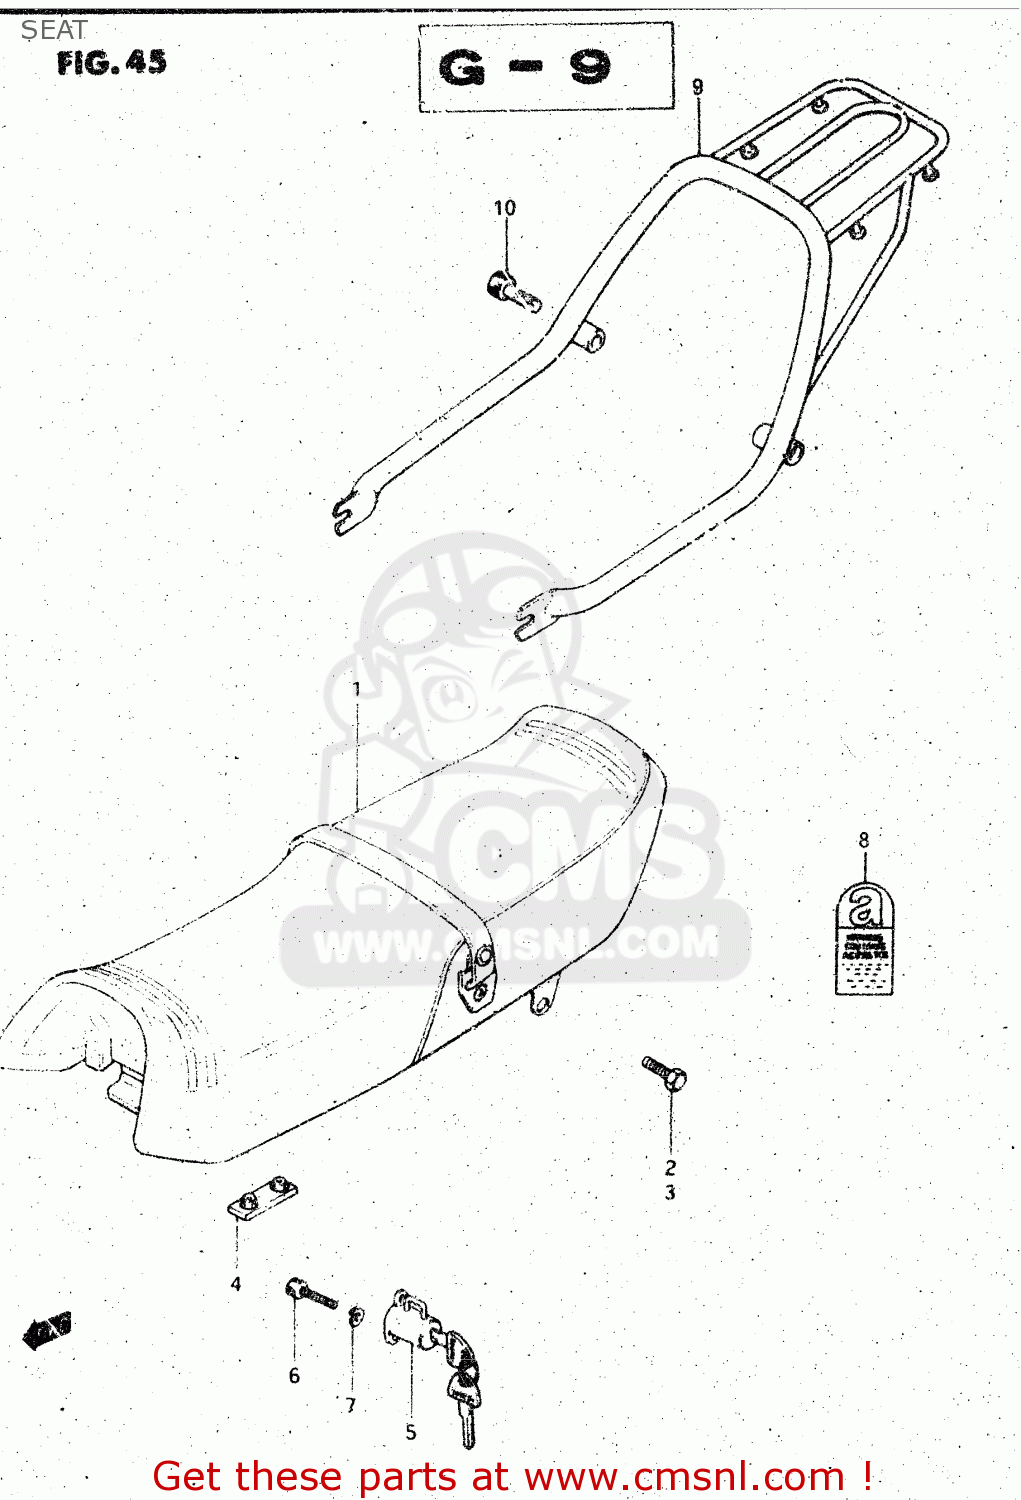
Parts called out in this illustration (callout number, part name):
1	SEAT ASSY (BLACK)
2	BOLT, LOWER
3	BOLT
4	CUSHION
5	LOCK SET,HELMET
6	BOLT 6X11
7	WASHER,LOCK
8	LABEL,ASBESTOS WARNING
9	CARREAR, SPORTS
10	BOLT(8X90)
